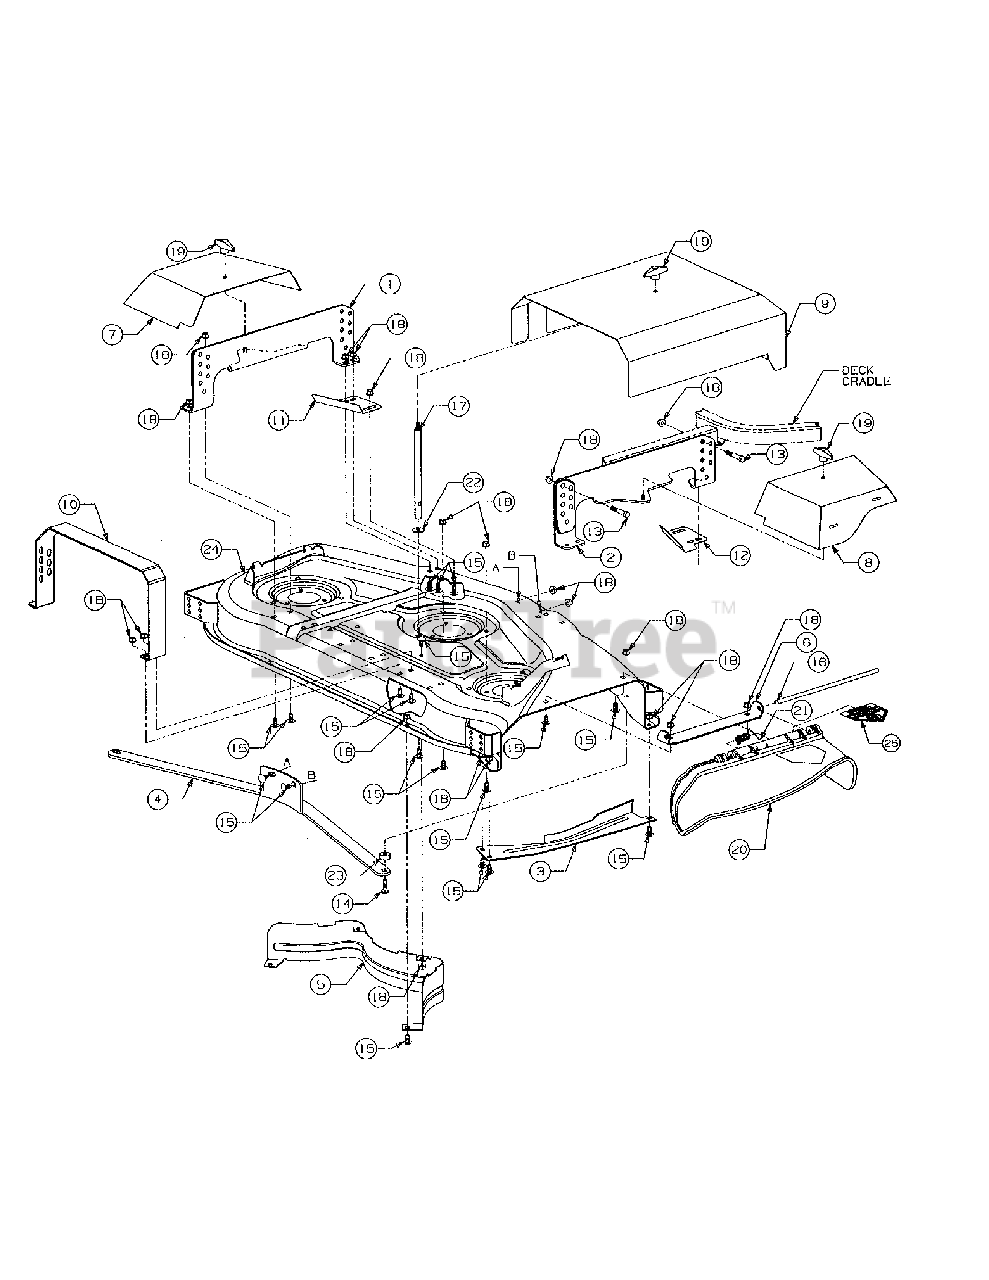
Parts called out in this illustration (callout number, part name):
9	Graphic, Belt Cover Front
9	Graphic 4814R, Belt Cover Right
10	Bracket, Belt Cober Support
11	Plate, LH Filler
12	Plate, RH Filler
13	Screw, Hex Cap, 3/8-16 x 2.25 Gr 5
14	Bolt, Carriage 3/8-16 x 1.25
15	Bolt, Sht Nk Carriage, 3/8-16 x .75 Gr 5
16	Pin, Hinge .375 x 12.55
17	Postm Belt Cover Support
18	Nut, Hex Flanged Lock 3/8-16
19	Knob, Wing Nut
20	Deflector, Chute
21	Spring, Torsion
22	Washer, Bell 3/8 x 1.125 x .062 Thk
23	Spacer, Front Bar
24	Housing Ass'y w/ Graphic, 48'' Mower
24	Graphic, Danger Cut Finger
24	Graphic, Danger
25	Graphic, Danger Cut Finger
